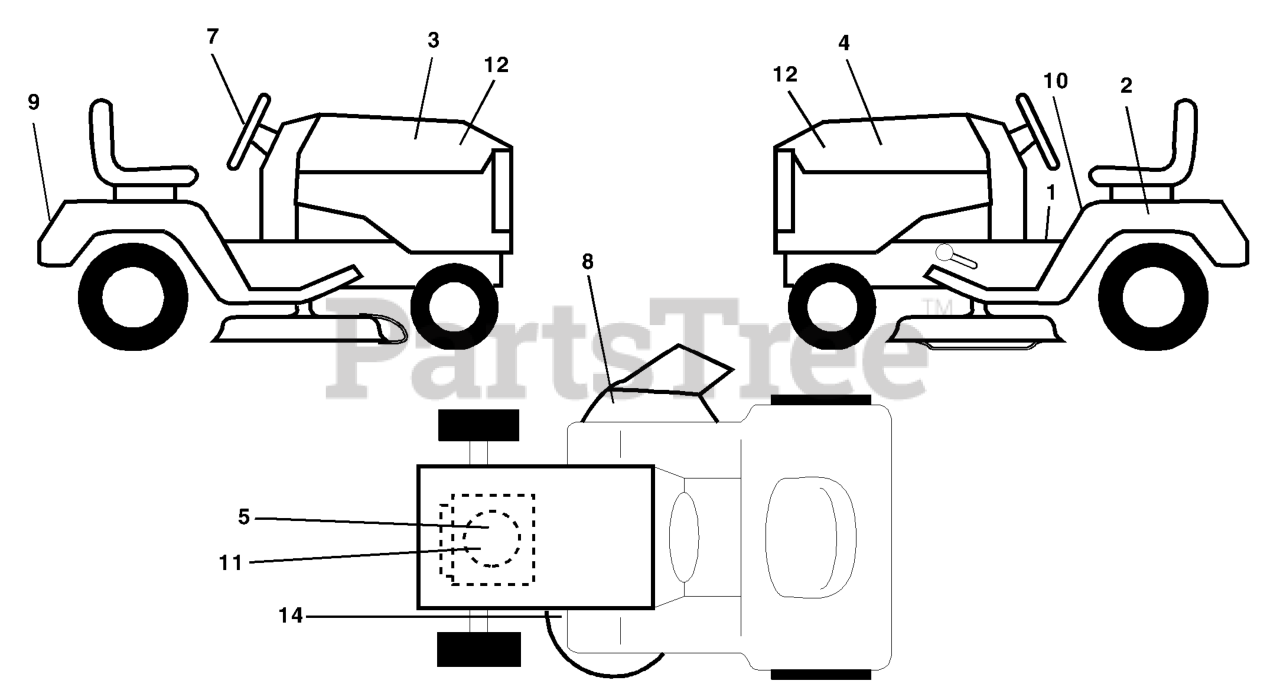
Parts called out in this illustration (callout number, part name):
2	DECAL BTRY SYMBOLS
3	DECAL, HOOD RH
4	DECAL HOOD LH
5	DECAL HP ENGINE
7	DECAL.WHEEL.STEERING.HUSQ.PERM
8	DECAL.WARN.KEEP.HAND.AWAY
9	DECAL, FENDER
10	DECAL FENDER DANGER
11	DECAL, ENGINE LOGO
12	DECAL, HOOD SIDE
14	DECAL V-BELT SCHEMATIC
